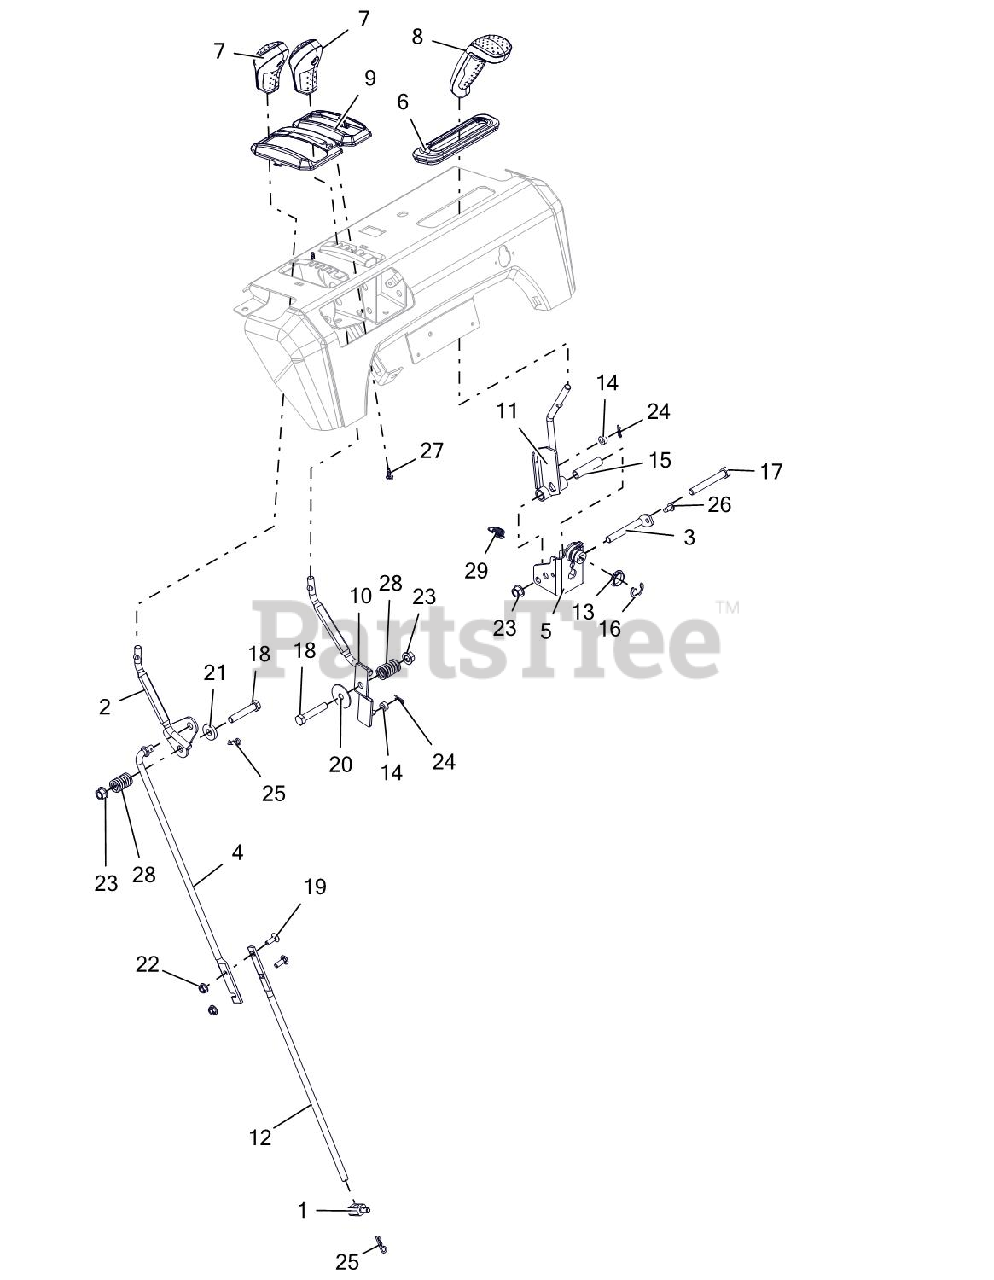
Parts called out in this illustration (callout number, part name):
1	PIVOT,SHIFT ROD .375-16(TRUNN)
2	WELDMENT,LG DASH SPEED CONTROL
3	ROD, PIVOT - INTERLOCK
4	ROD, SHIFT - UPPER
5	WELDMENT-CONTROL BRACKET-CHUTE
6	GROMMET, BOOT, QUICK TURN
7	KNOB, CONTROL, DASH
8	HANDLE, QUICK TURN, ASM
9	BEZEL, SHIFT - FRICTION SNOW
10	WELDMENT,LG DASH DEFL CONTROL
11	WELDMENT,LG DASH QT CONTROL
12	ROD, SHIFT-LOWER (LG DASH DLX)
13	BUSHING, POLYLINER-.75 SNAPIN
14	BSHG-SLV .265X.500X.219
15	SPCR, WHEEL .385X.500X2.00
16	E-RING .750X.050
17	@BLT-HEX .38-16X2.75 GR5 YWZC
18	@BLT-HEX .38-16X2.00 GR5 YWZC
19	@BLT-RDHDSQNK .25-20X.75 G5YZ
20	WSHR-FL-STL .380X1.50X.062 YWZ
21	WSHR-FL-STL .406X1.00X.188 YWZ
22	@NUT-LK-CTR-FLG .25-20 YWZC
23	@NUT-LK-TOP-FLG .38-16 YWZC
24	PIN-HAIR INT .06X.18X.77
25	PIN-HAIR INT .08X.18X1.18 YWZC
26	SCR-TAP .25-20X.50 HWH TR YWZ
27	SCR-TAP #10X.50 BOSS INDHXHD
28	SG-COMP .125X.781X1.250
29	SPRING-EXT .047X.438X1.45
